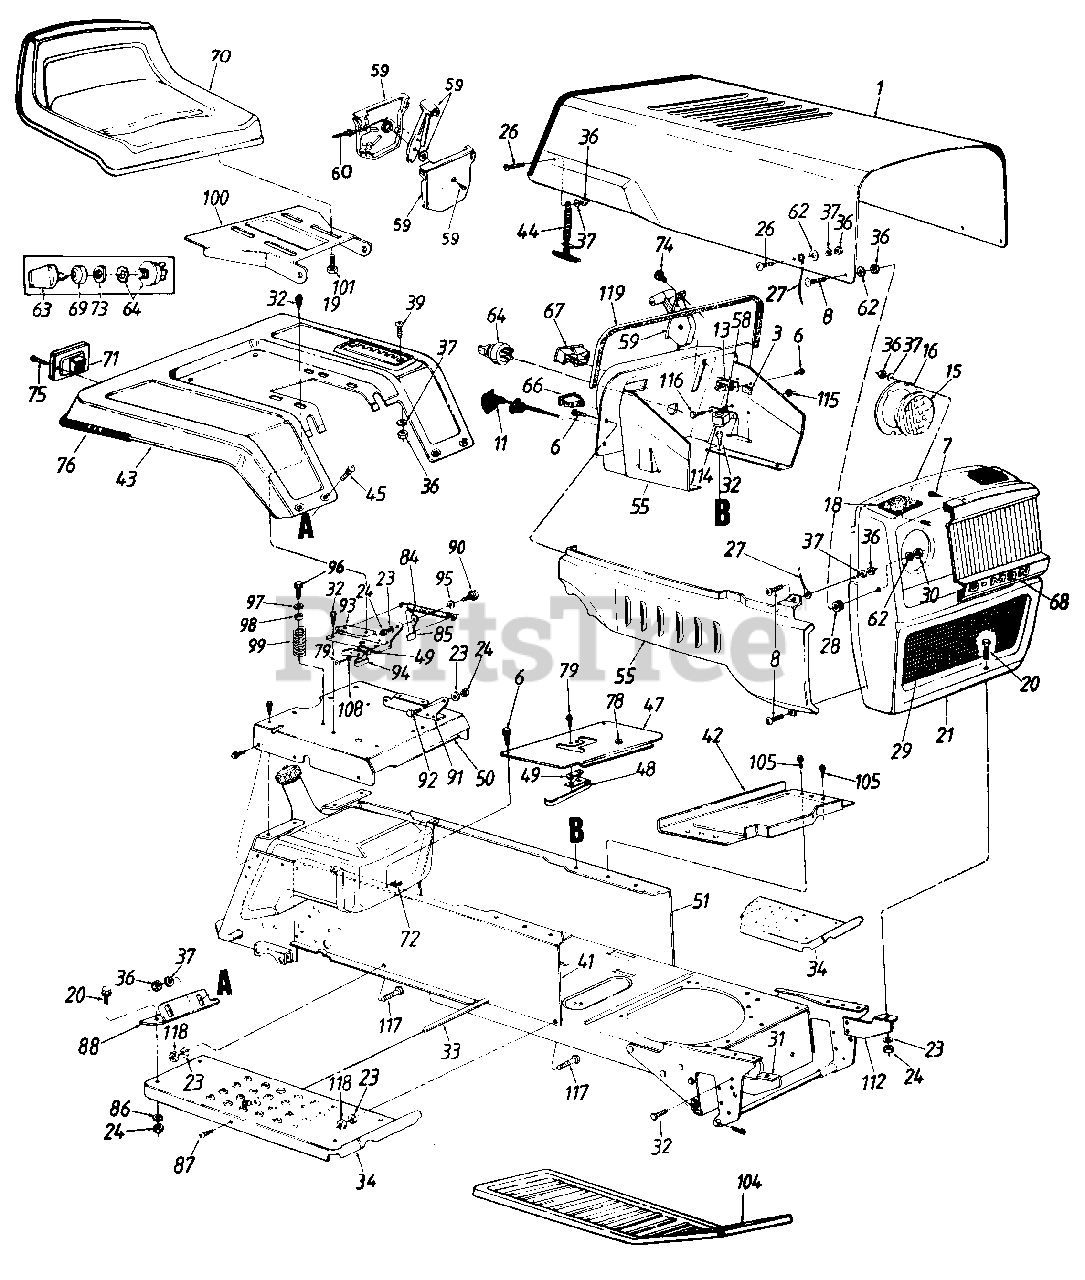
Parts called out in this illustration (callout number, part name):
6	Truss Mach. B-Tap Scr. #10 x .5" Lg.
7	Hex Wash Hd. AB-Tap Scr. #8 x .5" Lg.
8	Truss Mach. Scr.
11	Choke Control
13	Circuit Breaker
15	Headlight
16	Headlight Retainer
18	Foam Strip
19	Speed Control Index Brkt.
20	Hex Bolt 5/16-18 x .75" Lg.
21	Grille
23	L-Wash. 5/16" I.D.
24	Hex Nut 5/16-18 Thd.
26	Truss Mach. Scr. 1/4-20 x .5" Lg.
27	Hood Stop
28	Rubber Washer
29	Grille Insert
30	Hex Patch L-Nut 1/4-20 Thd.
31	Grille Mtg. Brkt. R.H.
32	Hex Wash. Hd. AB-Tap Scr. 5/16 x .75" Lg.
33	Running Board Rod
37	L-Wash. 1/4" I.D.
39	Truss Mach. Scr. 1/4-20 x .62"
41	R.H Side Frame
42	Battery Carrier
43	629 Rear Fender
44	Hood Latch Ass'y.
45	Carriage Bolt 1/4-20 x .50" Lg.
47	Transmission Panel
48	Reverse Safety Switch
49	Insulator Nut Plate
50	Seat Plate
51	L.H. Side Frame
55	Side Cover R.H.
58	Ext. L-Wash. 1/4" I.D.
59	Throttle Control Box Ass'y.
60	Throttle Control Wire 35" Lg.
62	Fl-Wash. .281" I.D. x .73" O.D.
63	Ignition Key
64	Ignition Switch
65	Dash Panel
66	Light Switch
67	Ammeter
68	Headlight Bezel
69	Ignition Switch Cap
70	Seat Ass'y.
71	Taillight Ass'y.
72	Speed Nut #1OZ
73	Ignition Switch Nut
74	Truss Mach. AB-Tap Scr. #10 x .5" Lg.
75	Truss Hd. AB-Tap Scr. #6 x .62" Lg.
76	Trim Strip 81"
78	Snap Bushing
79	Hex Wash. Hd. AB-Tap Scr. #8 x .50" Lg.
84	Ext. Spring 5.31" Lg.
85	Seat Lift Brkt.
86	Bell-Wash. .345" I.D. x .88" O.D.
87	Truss Maohine Scr. 5/16-18 x .75" Lg.
91	Seat Pivot Brkt. Support L.H.
92	Shld. Bolt :437" Dia. x .162"
93	Seat Pivot Brkt. Support R.H.
94	Spring Switch
95	Spr.-Wash..445" I.D.
96	Hex Wash. Hd. Tap Scr. 5/16-18 x .75" Lg.
97	Fl-Wash. .344" I.D.
98	Bushing
99	Compression Spring
100	Seat Pivot Bracket
101	Hex Tap Scr. 3/8-16 x :75"
104	Foot Pad
105	Hex Tap Scr. 1/4-20 x :5" Lg.
108	Fiber Washer
112	Grille Mtg. Brkt. L.H.
114	Solenoid
115	Hex Sems Nut 1/4-20 Thd.
116	Hex Bolt 1/4-20 x .5" Lg.
117	Rib Neck Bolt 5/16-24 x .75" Lg.
118	Hex Nut 5/16-24 Thd.
119	Trim Strip-29" Lg.
